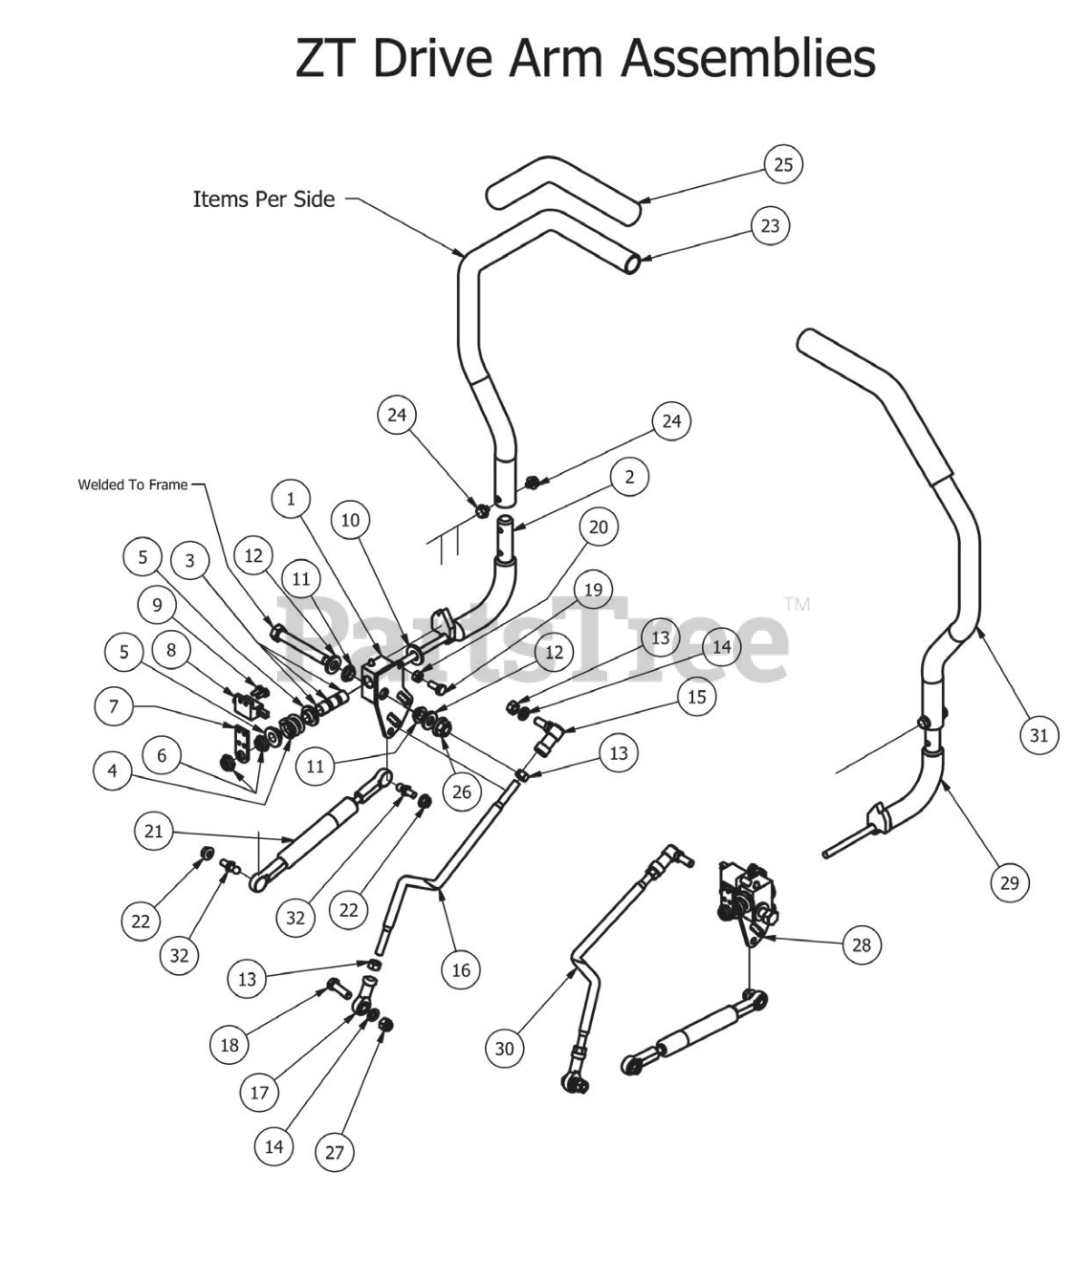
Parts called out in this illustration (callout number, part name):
1	2013 Drive Lever Housing (Left)
2	Steering Arm Elbow - Left
3	.507 ID Nylon Bushing
4	Drive Lever Spring
5	.515 ID Nylon Shoulder Washer
6	1/2" Nylcock Nut (1/2 Jam)
7	MZ Switch Bracket
8	Safety Switch
9	12-24x 1/2 HWH Bolt
10	.505 Nylon Spacer
11	Bushing for 2012 Drive Arms
12	.505x1x.125 Oil Impregnated washer
13	3/8" Fine Threaded Jam Nut
14	3/8" Lock Washer
15	3/8-24 Quick Release Ball Joint
16	Push Rod for ZT/CZT - Left
17	Spherical Rod End - Outlaw
18	3/8" x 1 1/4" Hex Bolt
19	5/16" x 3/4" Hex Bolt
21	Steering Damper For Outlaw
22	5/16" Flange Nut
23	ZT Direction Steering Arm (Left)
24	5/16-18 1/2 HWH Bolt-Steering
25	Rubber Grip
26	1/2-13 Hex Flange (GR.G) ZC
27	3/8 Nylock Nut
28	2013 Drive Lever Housing (Right)
29	Steering Arm Elbow - Right
30	Push Rod for ZT/CZT - Right
31	ZT Direction Steering Arm (right)
32	10mm Damper Ball Stud-Steering
